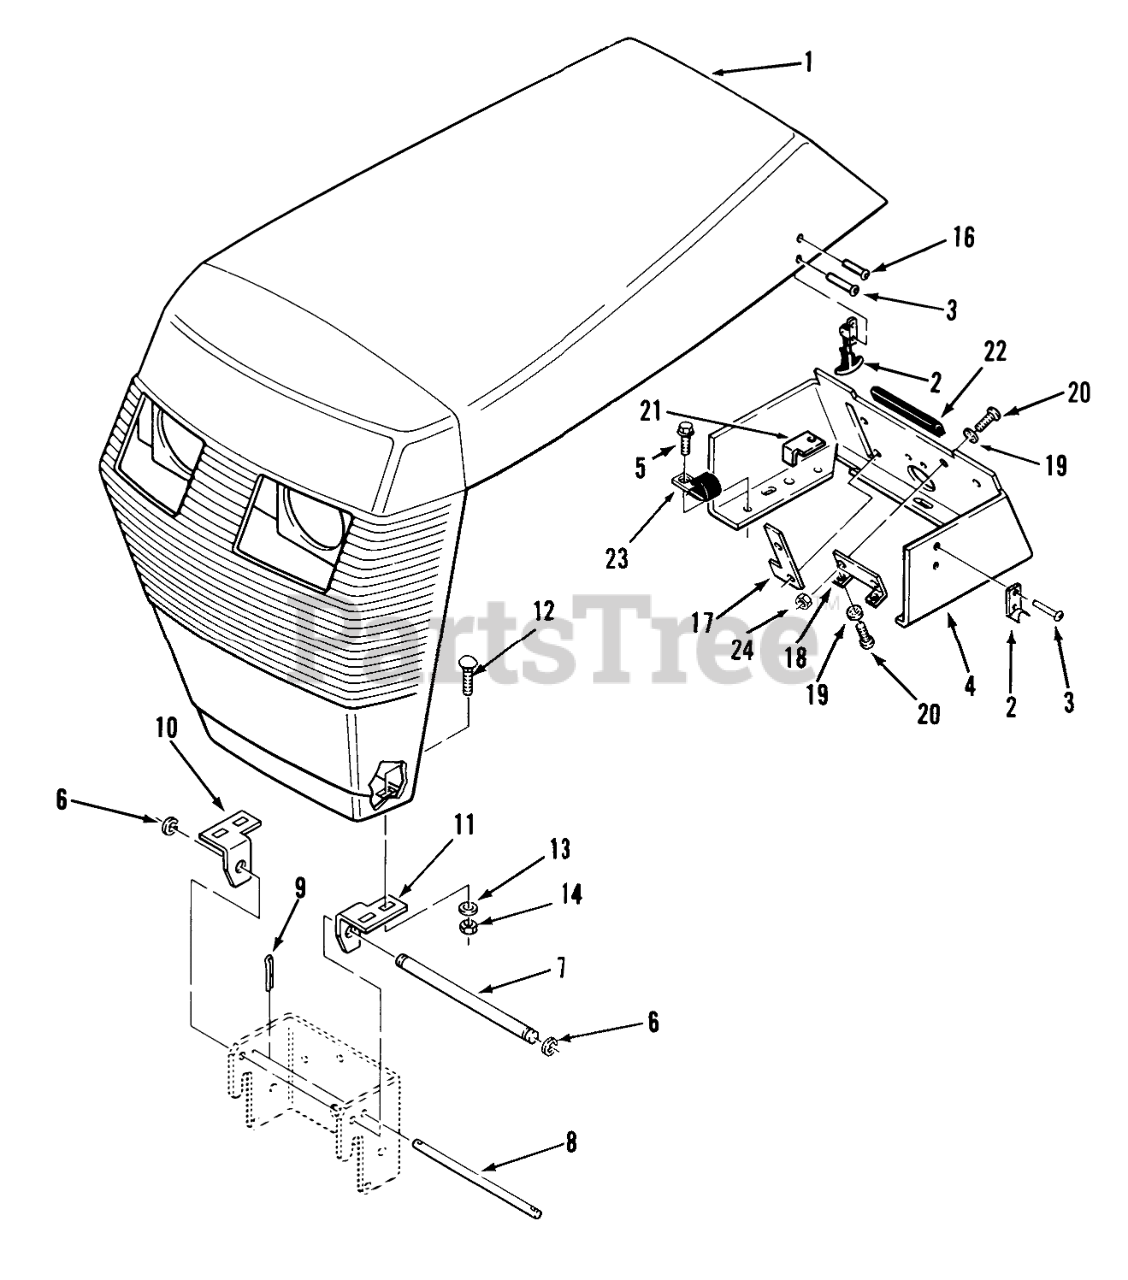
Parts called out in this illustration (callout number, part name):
2	ASSY-FLEX DRAW LATCH
3	RIVET
4	Hood Pivot Bracket RH
5	Hood Pivot Bracket LH
6	Bolt
7	Nut
8	ROD-GRILL PIVOT
9	RING-RETAINING
10	Latch Support Bracket
11	Hood Stop Rope
12	Control Panel
13	PLATE-BACKUP
14	SCREW BLACK
15	SPEED NUT
16	HOUSING-CONTL PANEL
17	Screw
18	EDGE TRIM 4IN OF 102896
19	Control Box Lower Support
20	Control Box Upper Support
21	RIVET
22	Control Extension
23	Nut
